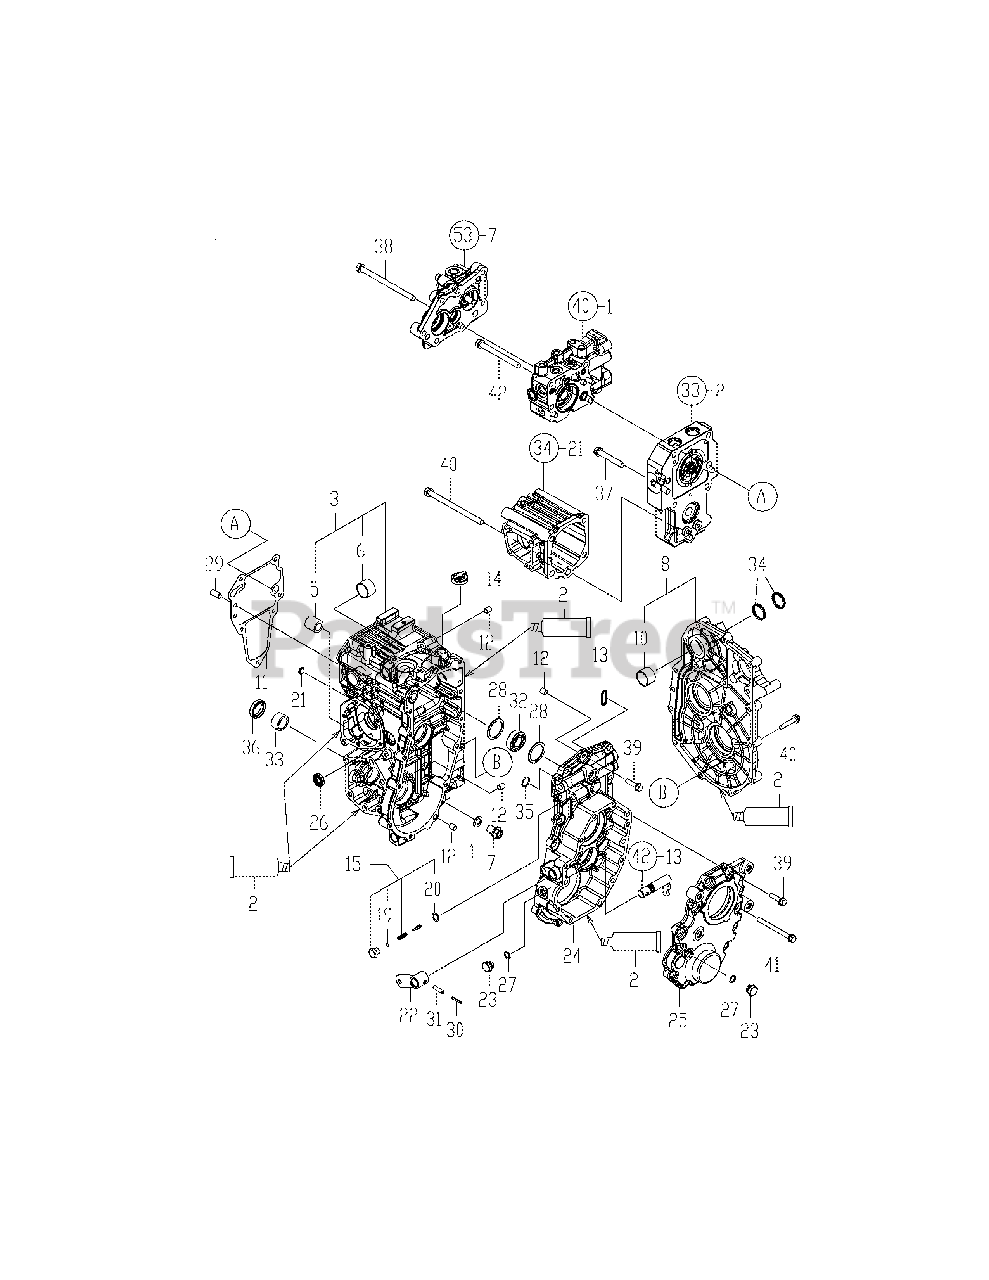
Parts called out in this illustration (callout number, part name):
3	Housing Kit, Mission
5	Joint, Strainer
6	Bearing, 28 X 20
7	Drain Bolt M14X20
8	Cover Kit, Mission
10	Bearing, 28 X 20
11	Packing, Center Case
12	Collar, 8X10X11.5
14	Valve, Vent 15
15	Relief Kit, Pto
20	Gasket, 12 X 1.0
23	Plug 9/16-18Unf
24	Case, Rear Pto
25	Cover, Rear Pto Case
30	Pin, 3.5A X 25
31	Pin, 6.0A X 25
33	Needle, 253216 Ntn
34	Packing, P 26.0
35	Packing, 19017
36	Seal, Tc253807
38	Bolt, 10 X 145
42	Bolt, 10 X 105
